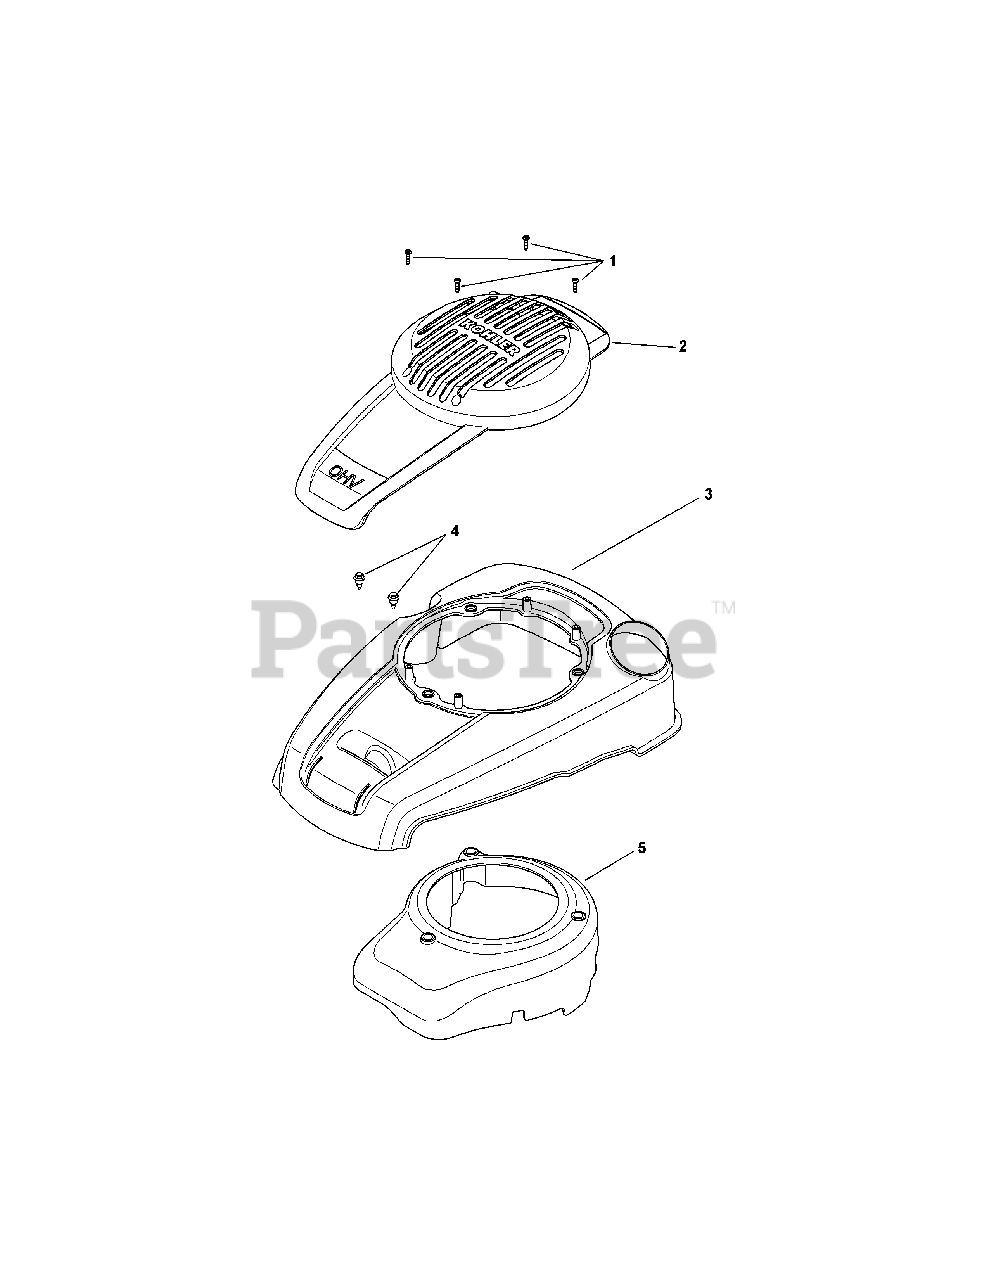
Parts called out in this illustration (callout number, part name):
1	Screw,#15 6-Lobe Pan Hd(Hi-Lo)
2	Insert, Engine Cover (Black)
3	Cover, Engine (Black)
4	Screw, Shoulder (M5)
5	Housing, Blower W/Elec Start
